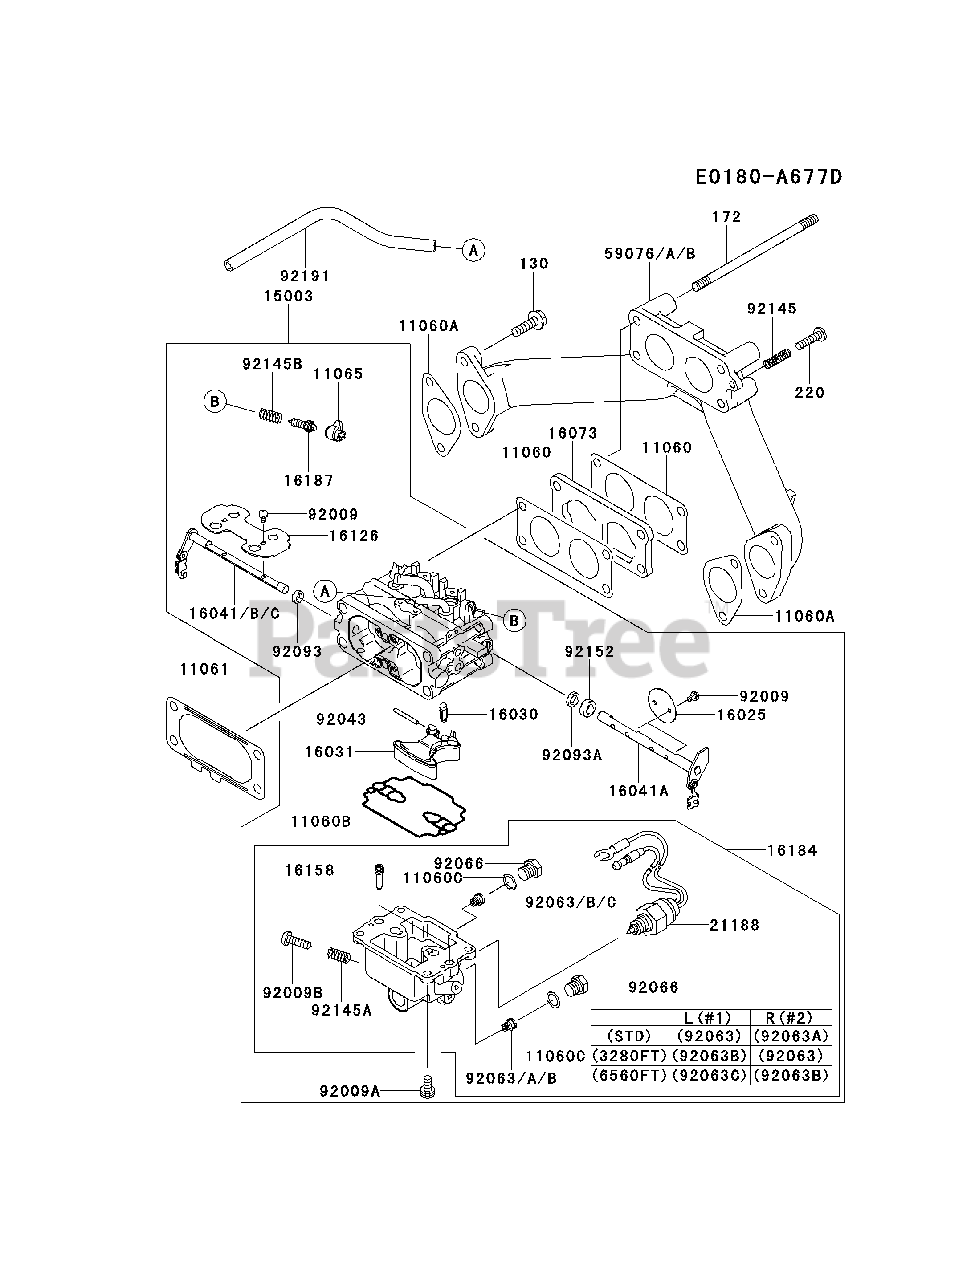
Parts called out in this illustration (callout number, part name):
130	BOLT-FLANGED,6X20
172	BOLT-STUD,6X105
220	SCREW-PAN-CROS,5X20
